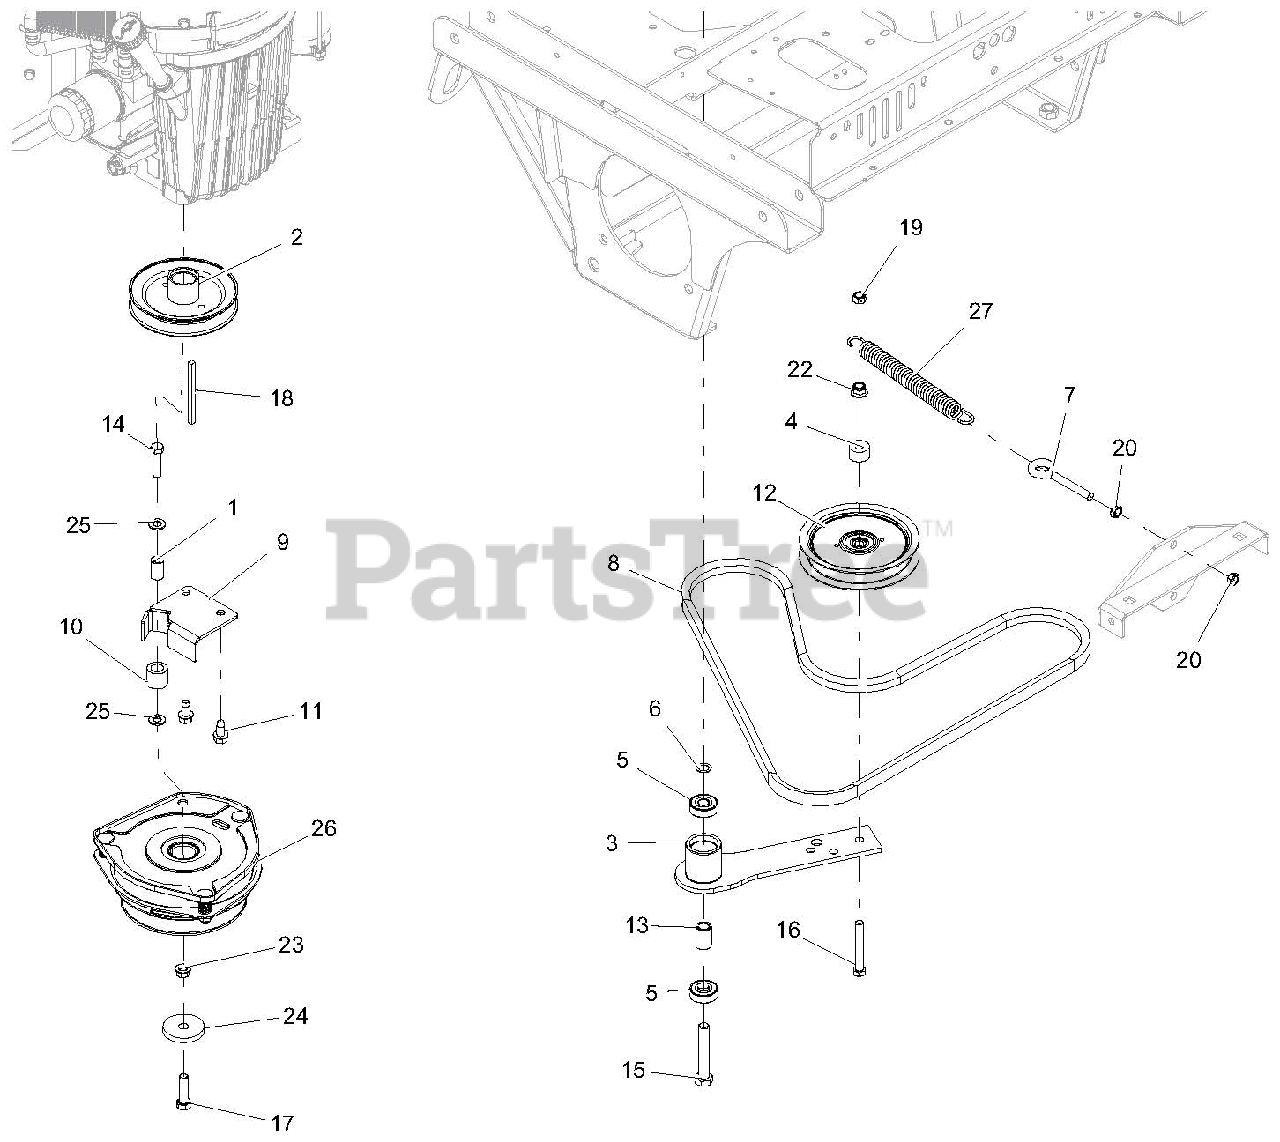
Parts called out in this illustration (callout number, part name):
1	BUSH.,S.391X.622X.95 ST REV A
2	SHEAVE, ENGINE 1.127 ID X 5.250 OD-BLACK
3	WLDMT, HYDRO DRIVE IDLER ARM-BLACK
4	SPACER .390X1.000X.562
5	BRG-BALL .500X1.375X.44
6	WASHER-FLAT-STL, .500 X .750 X .020
7	BOLT, EYE .375-16
8	BELT, B RAW COGGED
9	WLDMT, CLUTCH STOP
10	BUMPER, RUBBER .62 X 1.0 X .88 LG
11	SCR-TAP .38-16X.75 HWH TR YWZ
12	IDLER, FLAT - 5.00" X .75"
13	SPACER, .510 X .750 X 1.148
14	BLT-HEX .38-16X1.50 GR5 YWZC
15	BLT-HEX .50-13X3.00 GR5 YWZC
16	BLT-HEX .38-16X2.75 GR5 YWZC
17	BLT-HEX .44-20X1.50 GR8 YWZC
18	KEY-SQ .250X.250X3.50
19	NUT-LK-CTR .38-16 YWZC
20	NUT, JAM .375-16 YWZC
21	NUT-LK-NYL-FLG .50-13 YWZC
22	NUT-LK-NYL-FLG .38-16 YWZC
23	NUT, LK-TOP-FLG .38-16 YWZC
24	WSHR-FL-STL .469X2.00X.25 YWZC
25	WSHR-FL-STL.406X.812X.065 YWZ
26	CLUTCH-OGURA
27	SPRG, EXTENSION .120X.845X6.55 WLD
